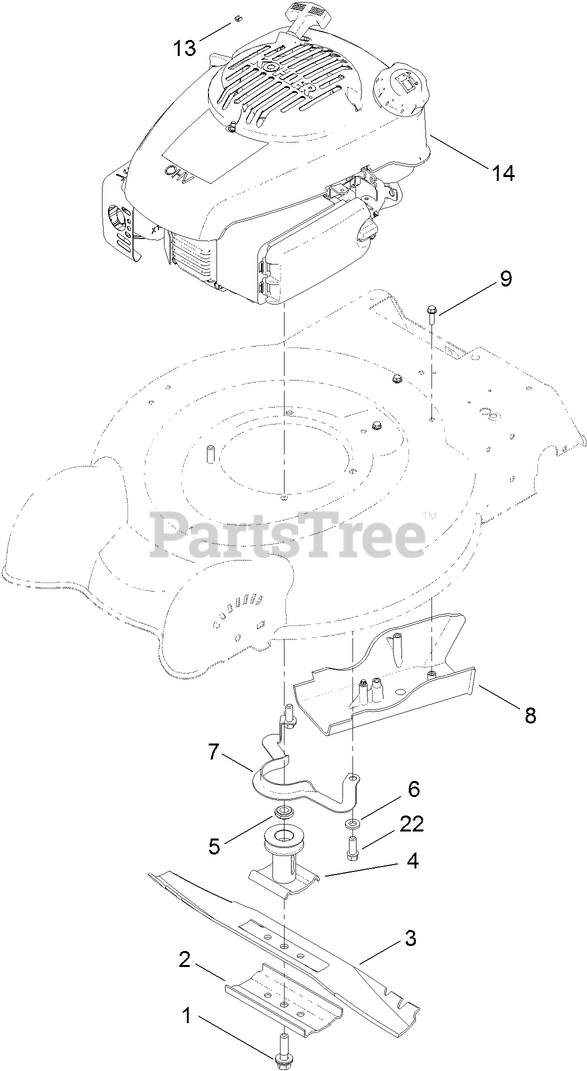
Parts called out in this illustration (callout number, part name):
2	SUPPORT-BLADE
4	DRIVER-BLADE
5	SPACER-DRIVER
6	SCREW-TAPTITE
8	COVER-BELT
9	SCREW-HWH
13	STOP-ROPE
22	WASHER-FLAT
